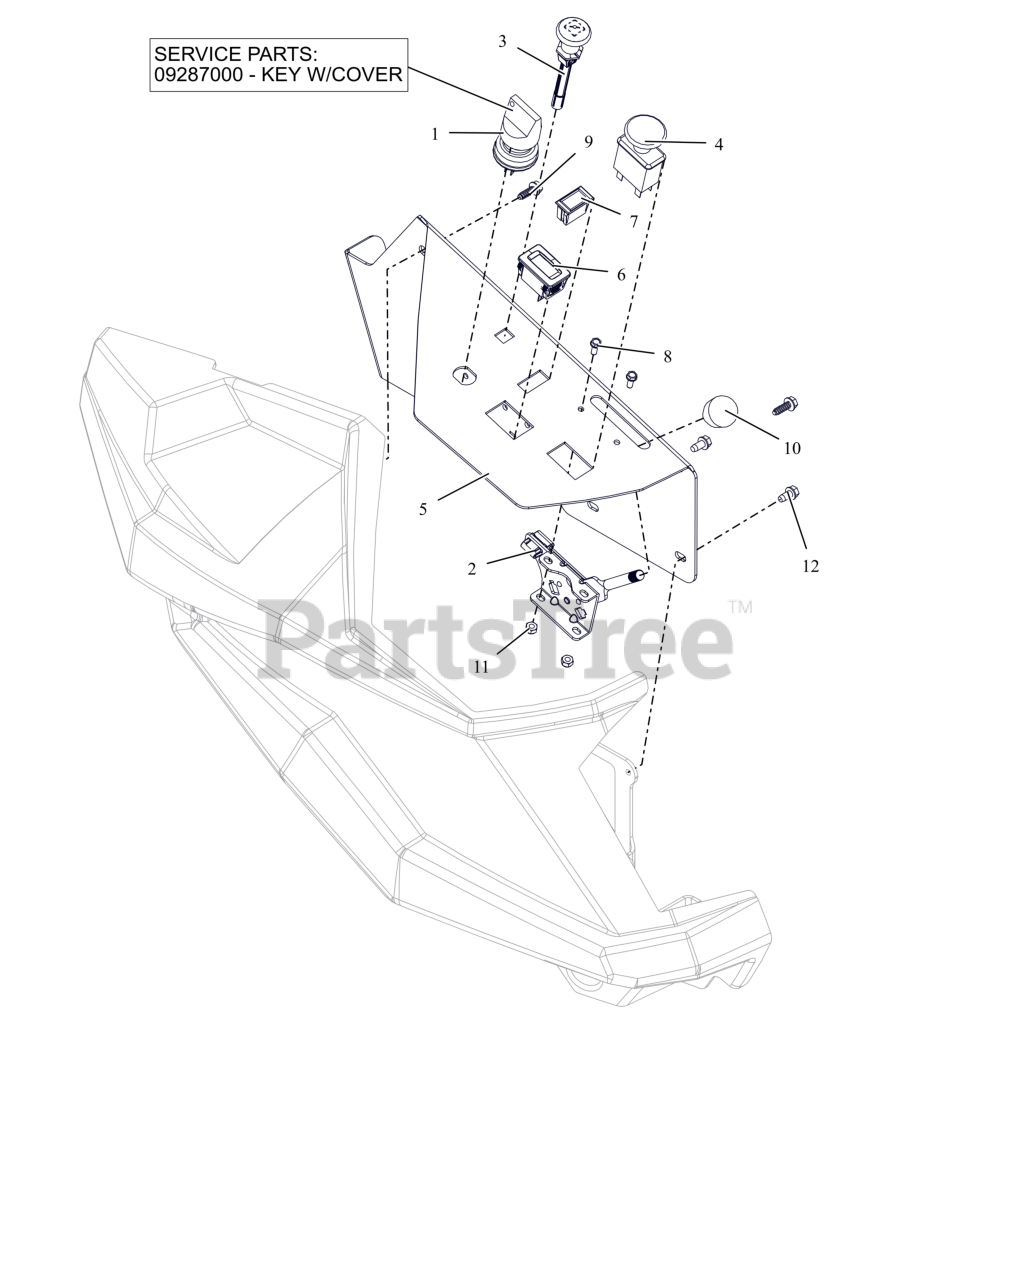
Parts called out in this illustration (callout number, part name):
1	SWITCH, IGNITION
1	KEY, W/ SHIELD
2	CABLE, PRO THROTTLE CONTROL
3	CABLE - CHOKE, SNAP-IN
4	SWITCH, CLUTCH
5	PANEL, HD CONTROL (RED)
6	HOUR METER
7	SWITCH,BLANK
8	BLT, HWH #10-24X.50 ZCC
9	SCR, PLASTITE-HWH 0.25 X 0.75 ZC120
10	KNOB-CONTROL-BLACK .38-16X.50
11	NUT-LK-NYL #10-24 G2 ZCC
12	SCR-TAP .25-20X.50 HWH ZCC
